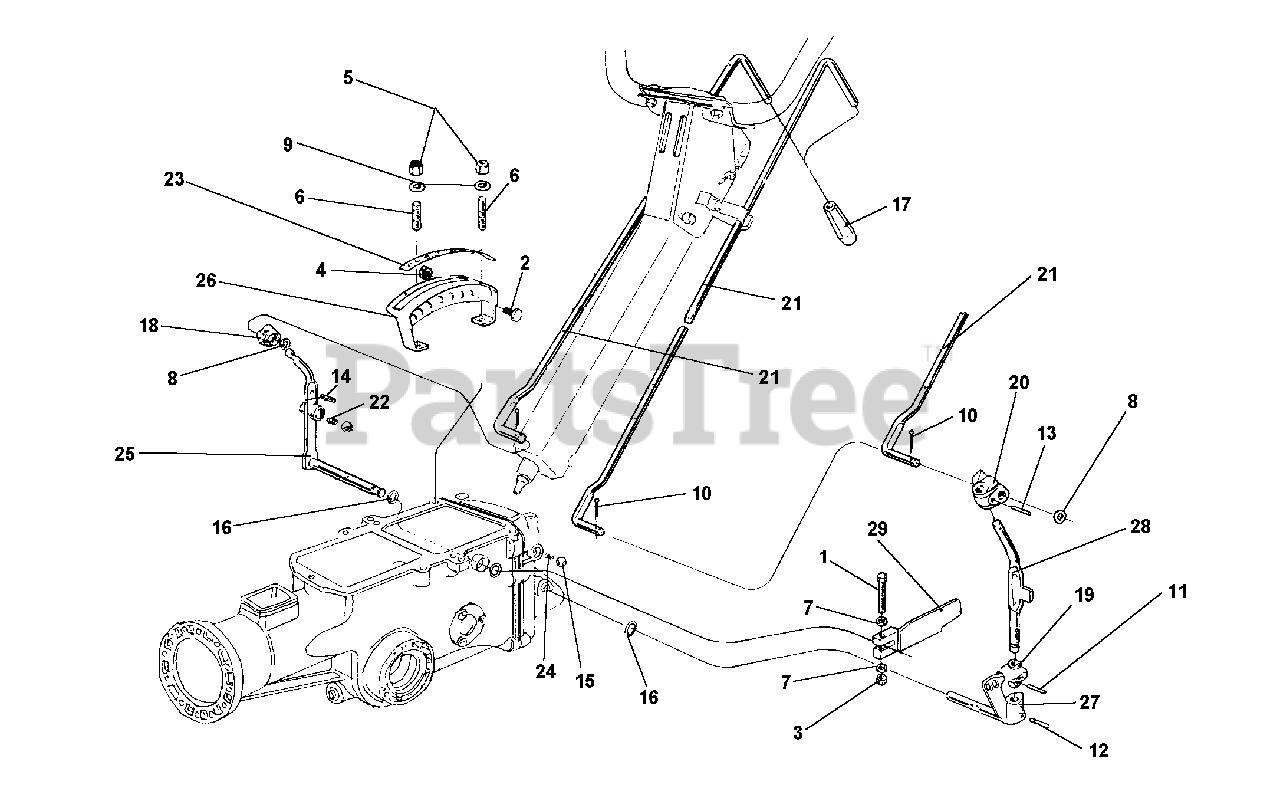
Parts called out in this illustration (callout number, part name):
1	SCREW M6 X 40
2	SCREW M8 X 14
3	NUT, SELF LOCKING M6
4	NUT, SELF LOCKING M8
6	STUD M8 X 38 X 14 X 20
7	FLAT WASHER 6.4
8	WASHER P10.5 X 18
9	SUPER WASHER 8 DIN 6796
11	LOCKING PIN 4 X 20 SPIRAL
13	LOCKING PIN 4 X 24 SPIRAL
14	LOCKING PIN SPIRAL
15	BALL 15/32 RIV RB-11.906
16	O-RING 115 11.91 X 2.62
18	JOINT, 715, 725, 735
19	PTO STOP RING
20	PTO ARTICULATION
21	ROD, CONTROL, POWER TILLER
23	SPEED DECAL, 715
25	GEARBOX LEVER
26	SPEED QUADRANT, 715
27	PTO CONTROL PIN, 715, 725, 735
28	PTO CONTROL LEVER
29	PTO LOCKOUT, 715
